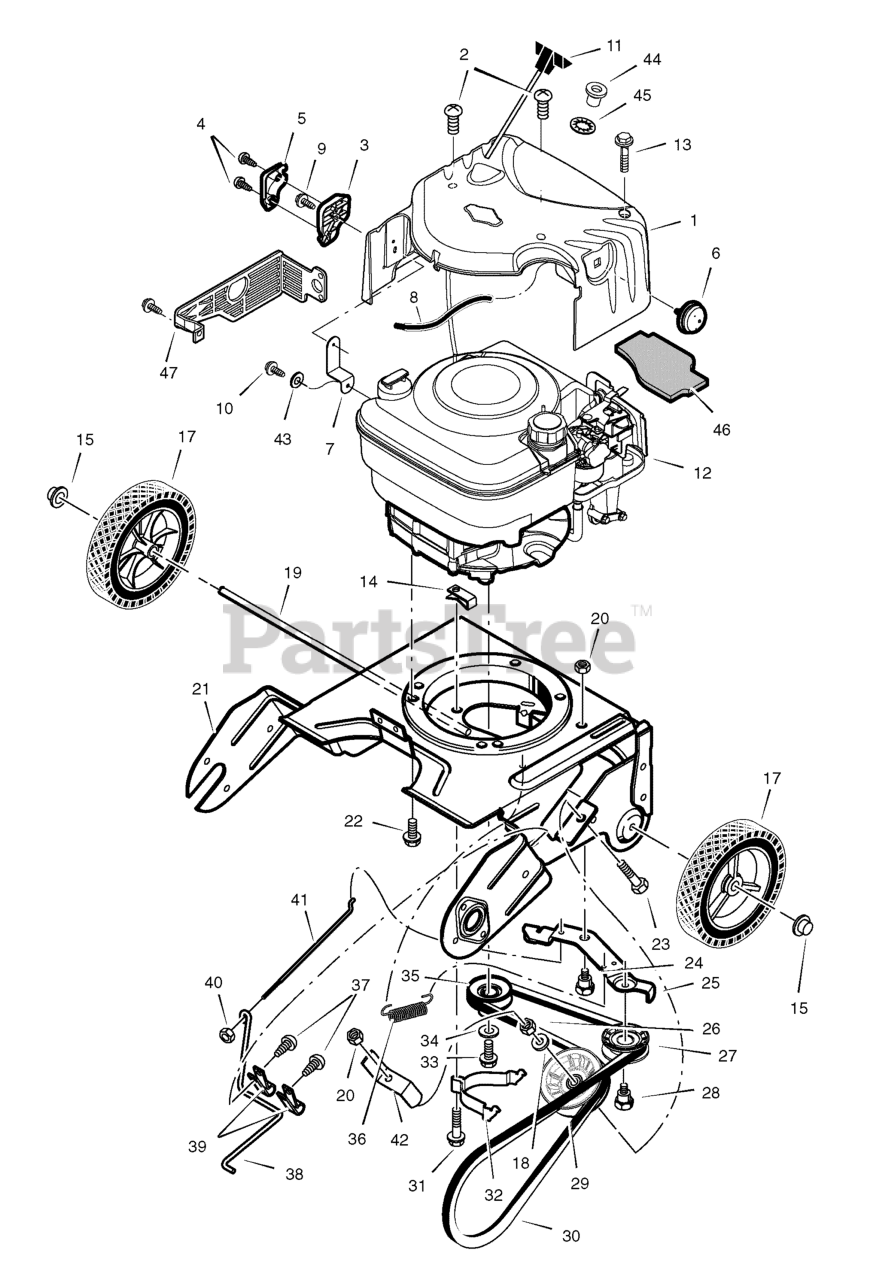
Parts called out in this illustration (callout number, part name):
1	Cover, Top
3	Base, Chute Rod
5	Cover, Chute Rod
6	Primerbulb, Red
7	Bracket, Engine Chute
11	Handle, Starter
12	Engine *
14	Retainer
15	Nut, Push Cap
17	Wheel & Tire
18	WASHER, Flat, 13/32
21	Frame, Motor Box
23	Bolt
24	Bolt, Shoulder
25	Bracket, Idler Arm
26	Nut
27	Pulley, V--Belt
28	Bolt, Shoulder
29	Pulley, Flat Idler
32	Guide, Belt
33	Screw
34	Washer
38	Arm, Brake
40	Nut
41	Rod, Adjustment
42	Guide, Belt
43	Lockwasher
44	Guide, Rope
45	Spring Grip Washer
46	Seal, Foam
47	Guard, Muffler
